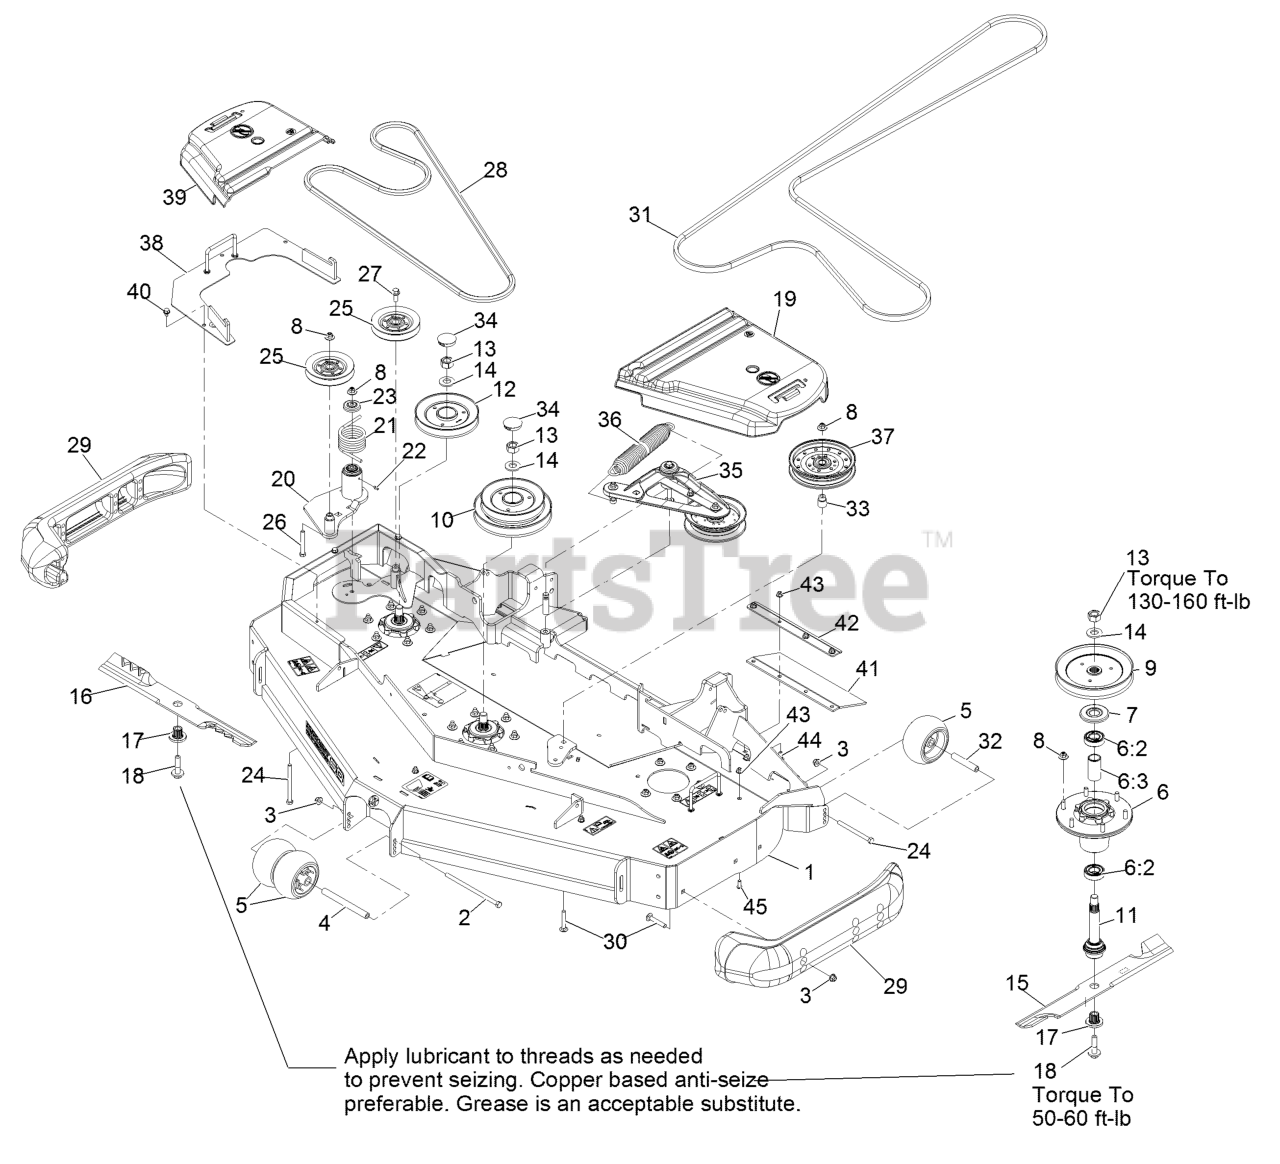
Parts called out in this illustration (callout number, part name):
1	DECK-RD60 NLZ, W/DECALS
2	SCREW-HH
3	NUT-HF, NI
4	SPACER-WHEEL
5	ROLLER-SCALP, ANTI
6	ASM-CUTTER HSG WITH BEARINGS
6:2	BEARING-BALL
6:3	SPACER-BEARING
7	GUARD,BEARING TOP .989
8	Nut-Nyloc 3/8-16 Flg
9	SHEAVE,BLADE DRIVE 7.25
10	SHEAVE, DOUBLE 60RD
11	ASM-SPINDLE AND SEAL
12	SHEAVE-RD REV DRIVE SERIE
13	NUT-HEX
15	Blade-Extreme 2, 20.50"
16	Blade-Low Lift 20.5, Rd60
16	Blade-Extreme 2-20.50, Rd60
17	BUSHING,SPLINED
18	SCREW,SEMS 1/2-20 X 2.19
19	COVER-BELT, LH
20	IDLER ASM
21	SPRING-TORSION
22	FITTING-GREASE
23	GUARD-TOP
24	SCREW-HH
26	SCREW-HH
27	SCREW-HHF
28	BELT
29	SKID-BUMPER, DECK
30	Bolt-Carriage 3/8-16 X 2 1/4
31	BELT
32	TUBE-SPANNER
33	BUSHING-IDLER
34	PLUG,BLACK NYLON 1.75
35	DECK IDLER ASM
36	SPRING-EXTENSION
38	COVER-DRIVE REVERSE
39	COVER-BELT, RH
41	GUARD-TIRE
42	SUPPORT-OUTER FLAP
43	NUT-HF, NI
44	SCREW-CARR
45	SCREW-HSBH
